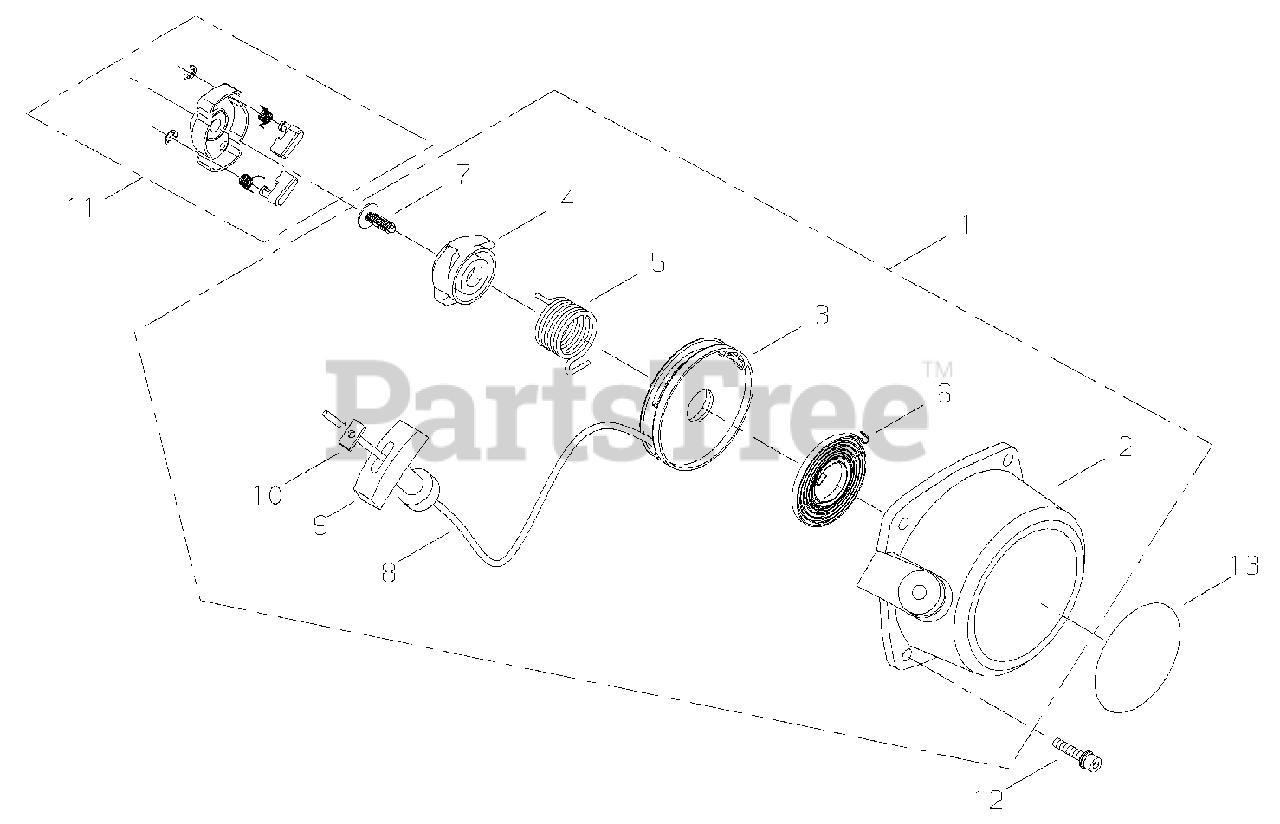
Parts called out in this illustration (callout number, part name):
2	CASE, STARTER
3	REEL, ROPE
4	CAM
5	SPRING
6	SPRING, REWIND
7	SCREW - 5
8	ROPE, STARTER
9	GRIP, STARTER
10	STOPPER
11	STARTER PAWL ASSY
12	SCREW - 4X12
13	NAME PLATE
